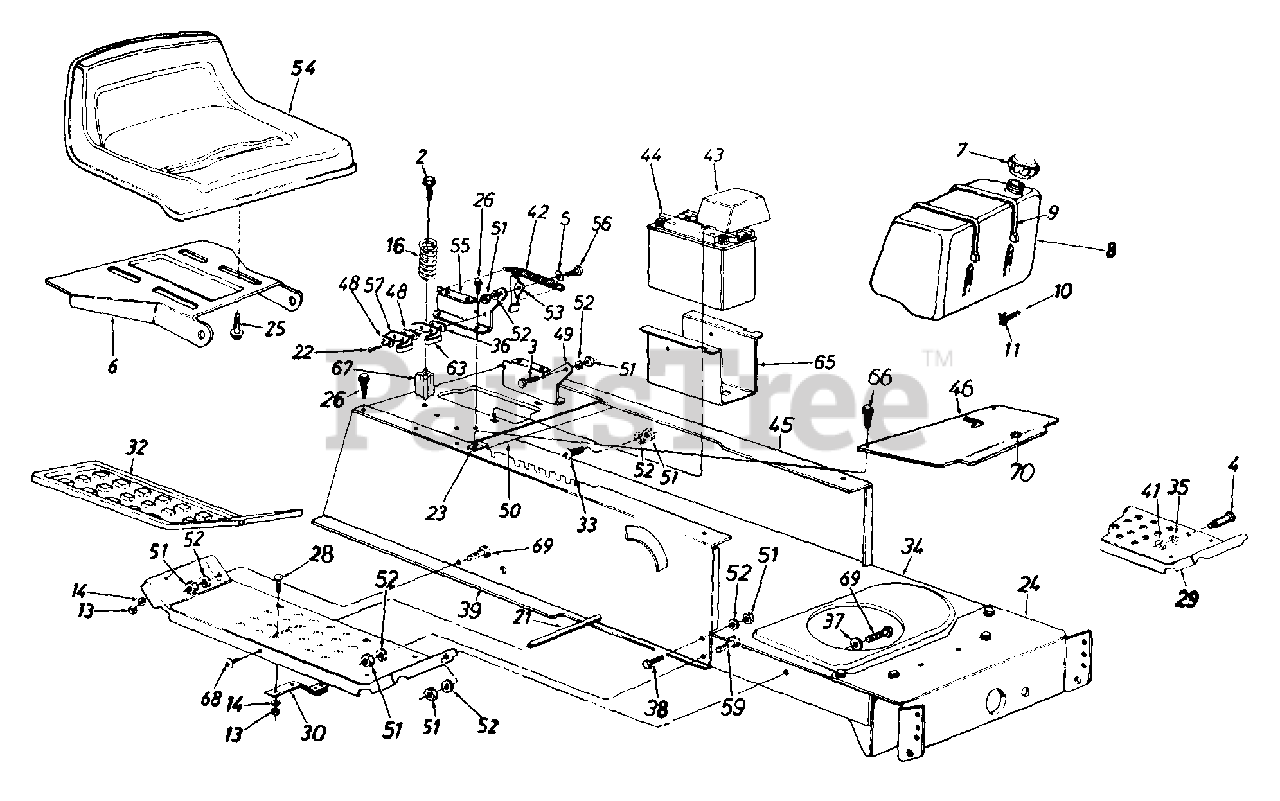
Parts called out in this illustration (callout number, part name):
2	Hex Wash. Hd. Tap Scr. 5/16-18 x 3.25" Lg.
3	Shld. Bolt .437" Dia. x .162"
4	Shld. Bolt .50" Dia. x .84"
5	Spr-Wash. .445" I.D. x .75
7	Fuel Cap
8	Fuel Tank
9	Tie Strap
10	Fuel Line
11	Hose Clamp
13	Hex Nut 1/4-20 Thd.
14	L-Wash. 1/4" I.D.
16	Compression Spring
21	Running Board Rod
22	Hex Wash. Hd. AB-Tap Scr. #8 x .50" Lg.
23	Speed Nut #10Z
25	Hex Tap Scr. 3/8-16 x .75"
26	Hex Wash. Hd. AB-Tap Scr. 5/16 x .75" Lg.
28	Carriage Bolt 1/4-20 x .62" (134A606F190)
32	Rubber Foot Pad - L.H.
32	Rubber Foot Pad - R.H.
33	Truss Mach. Scr. 5/16-18 x .75" Lg.
34	Lower Frame
35	L-Wash. 3/8" I.D.
36	Insulator Boss Plate
37	Fl-Wash. .344" I.D. x .625" O.D.
38	Hex Bolt 5/16-18 x .75" Lg.
42	Extension Spring 5.31" Lg.
43	Battery Cover
44	12-V Battery
49	Seat Pivot Brkt. Support - L.H.
52	L-Wash. 5/16" I.D.
53	Seat Lift Brkt.
54	Seat (134T696H190)
54	Seat (134A606F190)
55	Seat Pivot Brkt. Support - R.H.
56	Shld. Bolt .437" Dia. x .268"
57	Spring Switch
59	Hex Wash. TT-Tap Scr. 5/16-18 x 7/8" Lg.
63	Safety Switch (Seat)
65	Battery Tray
66	Truss Mach. B-Tap Scr. 410 x .5" Lg.
67	Spring Spacer
68	Pan Hd. Cutting Scr. 5/16-18 x .75" Lg.
69	Hex Bolt 5/16-18 x .75" Lg.
70	Snap Bushing
